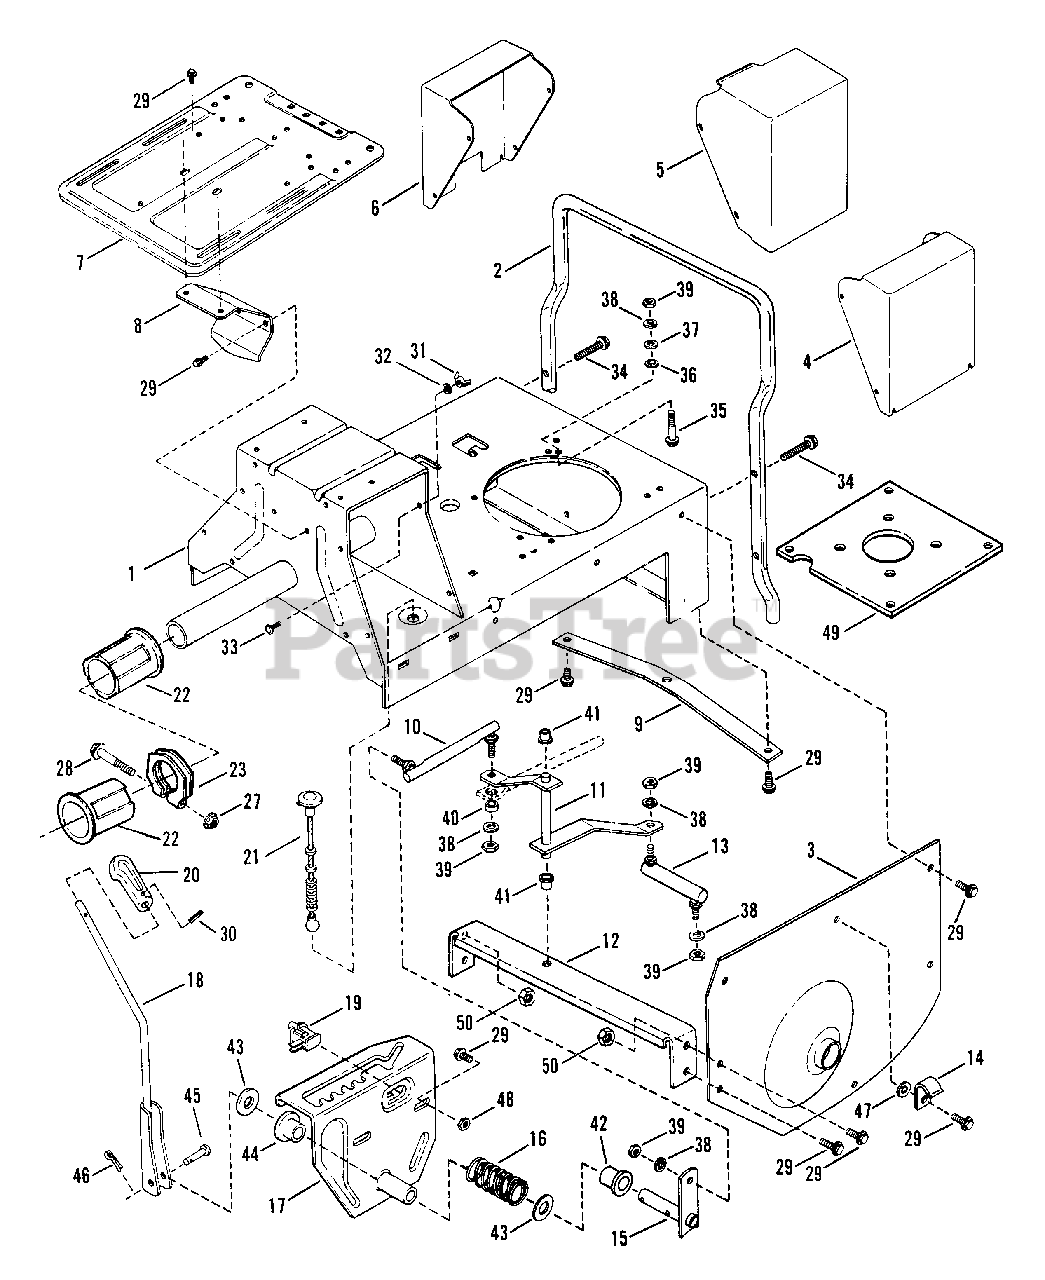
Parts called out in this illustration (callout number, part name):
1	MAIN CASE, Standard
1	MAIN CASE, 14 HP
2	BUMPER, Rear
3	FENDER, Left Hand
4	COVER
5	COVER, Battery
6	COVER, Switch
7	BASE, Seat Support
9	PLATE, Hitch
10	LINK, Shift, Long
11	ARM, Shift
12	BRACE, Cross
12	CROSS BRACE
13	LINK, Shift, Short
14	CLIP, Wiring
15	ARM, Shift Handle
16	SPRING, Shift Handle
17	DETENT, Shift
18	HANDLE, Shift
19	SWITCH, Seat
20	KNOB, Shift Handle
21	CABLE, Deck Support
22	BUSHING, Main Tube
23	CLAMP, Main Tube
27	NUT, 5/16 - 24 Hex Flange Lock
28	SCREW, 5/16 - 24 x 2-1/2" Hex Cap
29	SCREW, 5/16 - 18 x 5/8" Self-Tapping
30	ROLL PIN, Deck Handle 3/16 - 3/4
31	WING-NUT, #10-24 Locking
32	RETAINER, Bolt
33	FASTENER, 1/4 x 3/4" Ratchet
34	SCREW, 5/16 - 18 x 1-1/2" Self-Tapping
35	SCREW, 5/16 - 24 x 1-1/2" Hex Head Cap
36	RETAINER, Bolt
37	WASHER, 5/16" Flat
38	WASHER, 5/16" Split Lock
39	NUT, 5/16-24 Hex
40	ROLLER
41	BUSHING, Nylon
42	BUSHING, Nylon
43	WASHER, Thrust
44	BUSHING, Nylon
45	CLEVIS-PIN
46	COTTER-PIN, 3/32 x 3/4"
47	WASHER, 5/16 Internal Tooth Lock
48	NUT, 5/16 - 18 Hex
49	PLATE, 14 HP Engine
50	NUT, 5/16 "C" Hex Flange Lock
